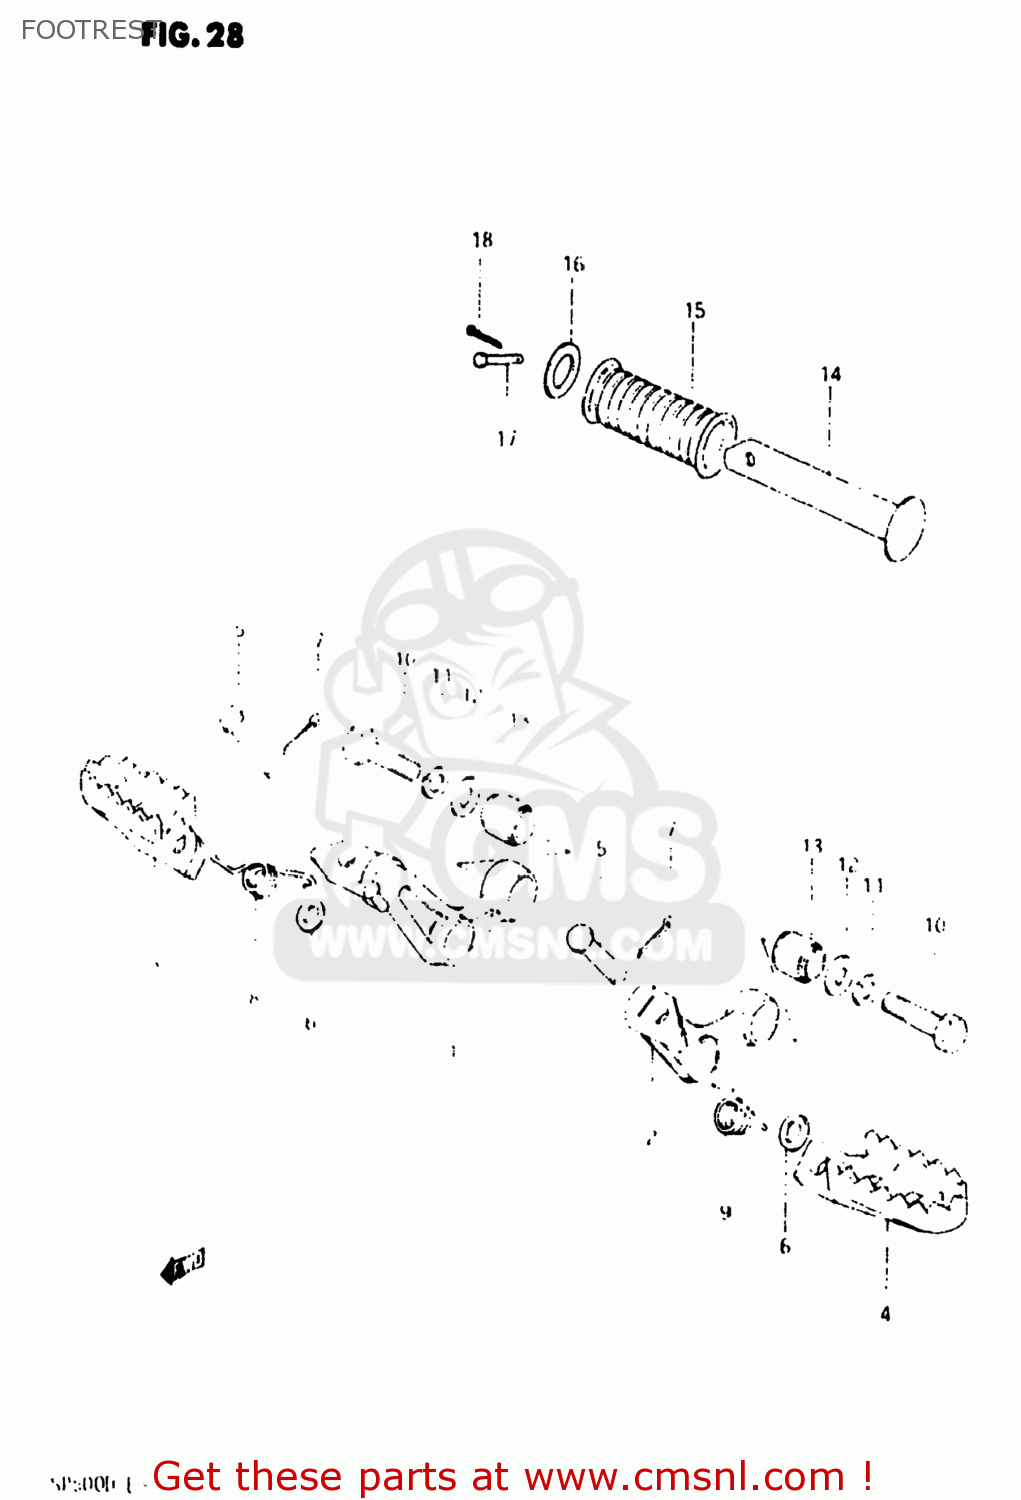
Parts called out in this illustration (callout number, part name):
1	BAR,FRONT FOOTREST
2	BAR,FRONT FOOTREST,LEFT
3	FOOTREST,RIGHT
4	FOOTREST
5	PIN
6	WASHER
7	PIN 20X20
8	SPRING
9	SPRING
10	BOLT
11	LOCK WASHER
12	WASHER (10.1X21X2.3)
13	BUSH
14	BAR,PILLION FOOTREST
15	RUBBER,PILLION FOOTREST
16	WASHER (19.5X32X2)
17	PIN
18	PIN 20X20
